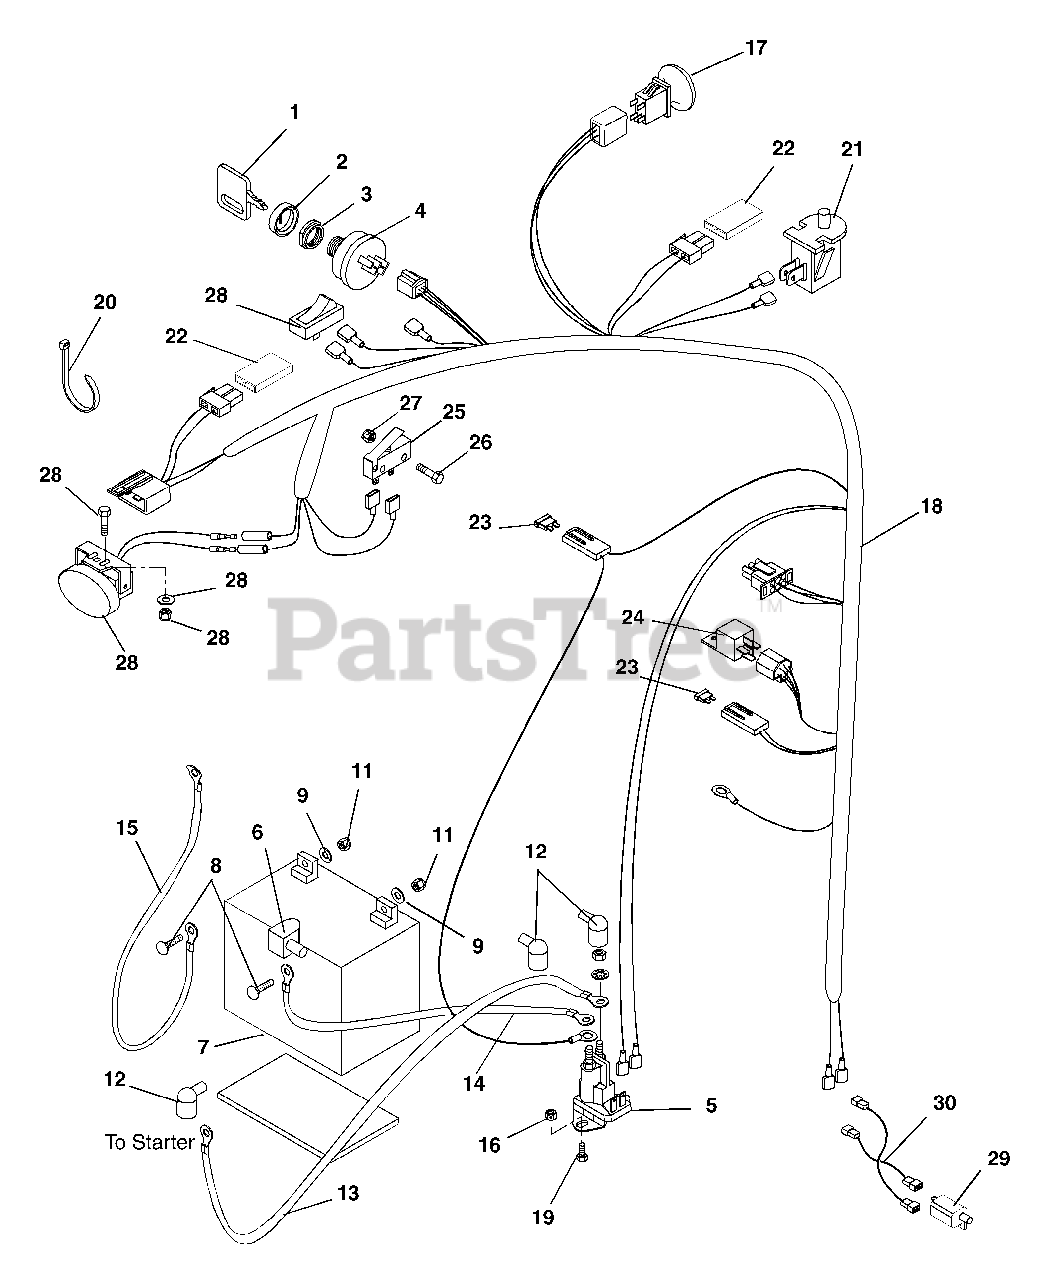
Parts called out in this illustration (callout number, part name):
1	Key with Cap
2	Cap, Ignition Switch
3	Nut, Panel .625-32
4	Key Switch
5	Solenoid
6	Insulator
8	Bolt, Hex .25-20 x .75 Grade 5
9	Washer, Flat Steel .281 x .62 x .065
10	Washer, Locking .25 x .062 Regular
11	Nut, Hex .25-20
12	Boot, Eyelet Terminal
13	Cable, Positive Battery
14	Starter Cable 13"
15	Starter Cable 16"
16	Nut, Spin Lock Flange .312-18
17	Switch, Clutch With Retainer
18	Harness, Wire
19	Screw, Tapping 10-24 x .375 Hex Washer Head
20	Cable Tie
21	Switch- Snap Mounting (N.O.)
22	Diode, Connector Shell
23	Fuse, 25 AMP
24	Relay
25	Switch, Parking Brake
26	Screw, Machine 2-56 x .75
27	Nut, Nylock 2-56
28	Light Kit
29	Switch- Single Pole (N.O.)
30	Jumper, Harness
